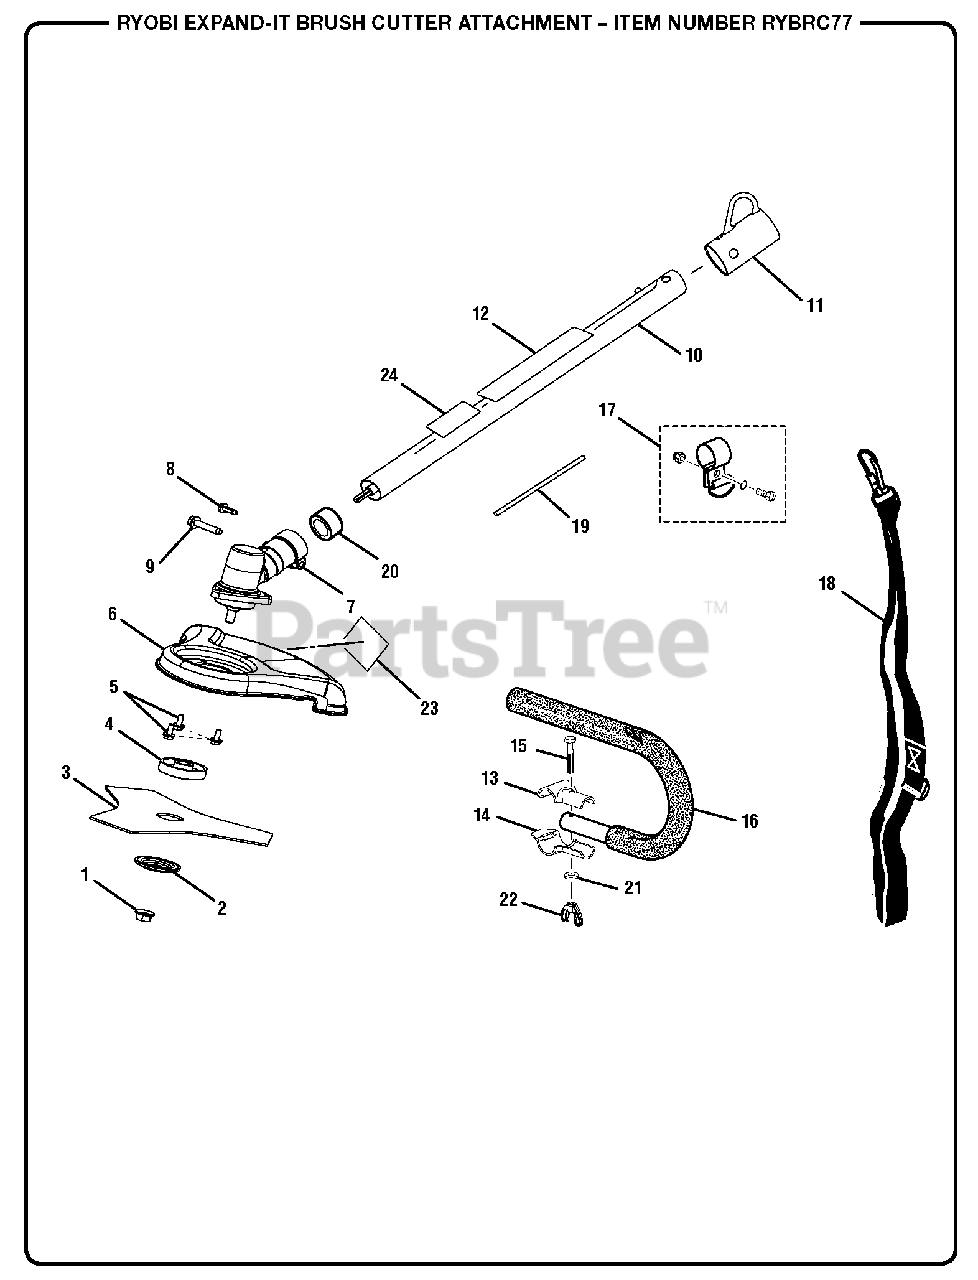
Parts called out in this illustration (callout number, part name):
1	Blade Nut (M8, Left Hand Threads)
2	Cupped Washer
3	Blade (Tri-Arc(R))
4	Flanged Washer
5	Screw w/Washer (10-24 x 1/2 in., Hex Hd)
6	Brush Cutter Guard
7	Gear Head Assembly
8	Screw (10-24 x 5/8 in.)
9	Screw (1/4-20 x 1-1/4 in)
10	Boom Assembly
11	Hanger Cap
12	Warning Label
13	Top "J" Handle Clamp
14	Bottom "J" Handle Clamp
15	Bolt (1/4-20 x 1-1/2 in., Hex Hd)
16	"J" Handle and Grip
17	Strap Hanger
18	Shoulder Harness Assembly
19	Head Locking Tool
22	Wing Nut (1/4-20)
23	Logo Label
24	Logo Label
